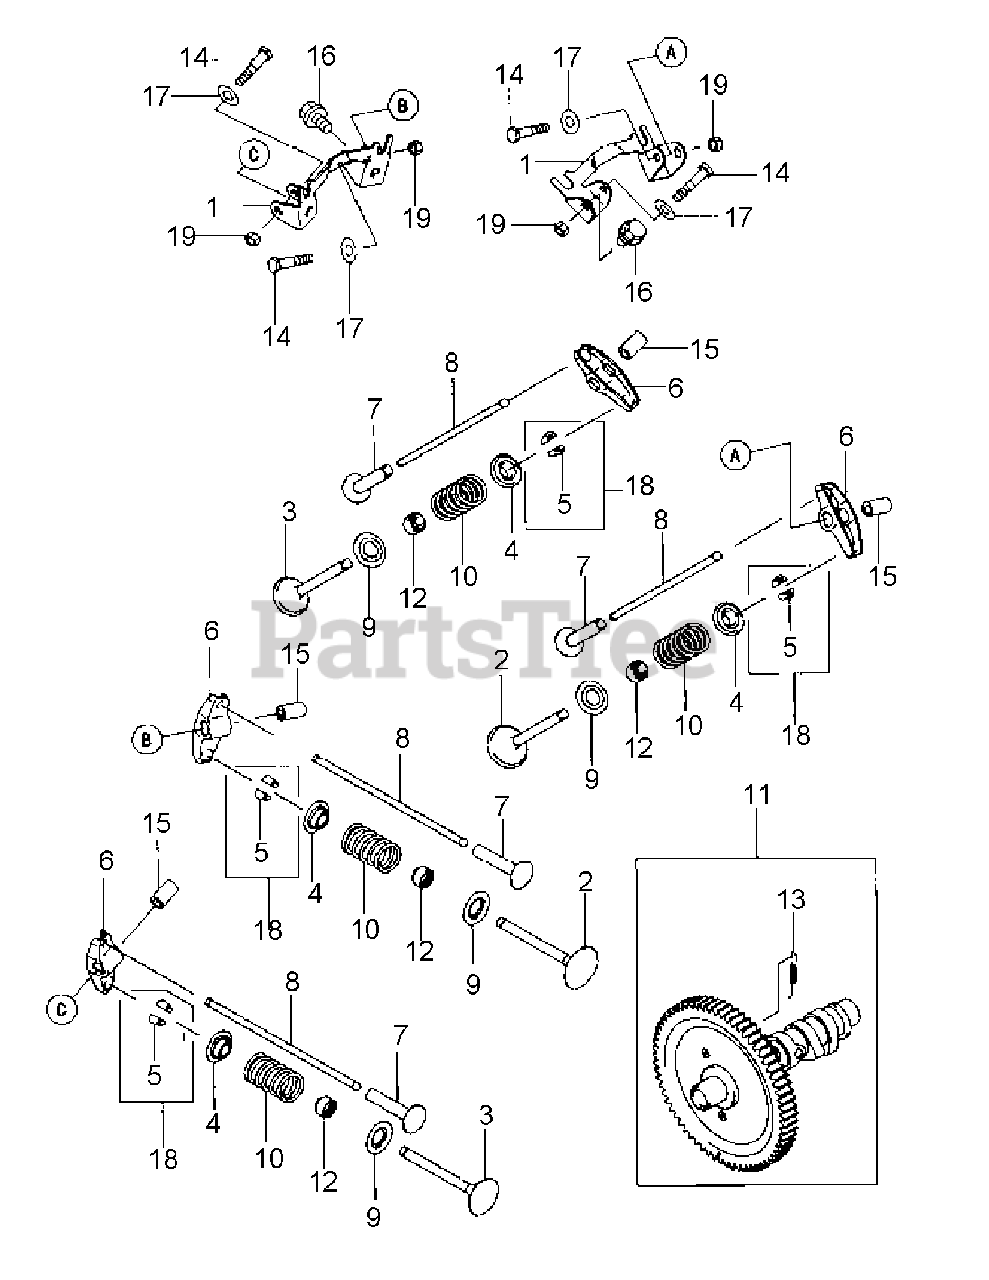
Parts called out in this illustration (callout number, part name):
3	EXHAUST VALVE
4	VALVE SPRING RETAINER
6	ROCKER ARM
11	CAMSHAFT COMPLETE
12	OIL SEAL, VSB 7x12x5.5x9.7
17	WASHER, 8.1x18x.5
